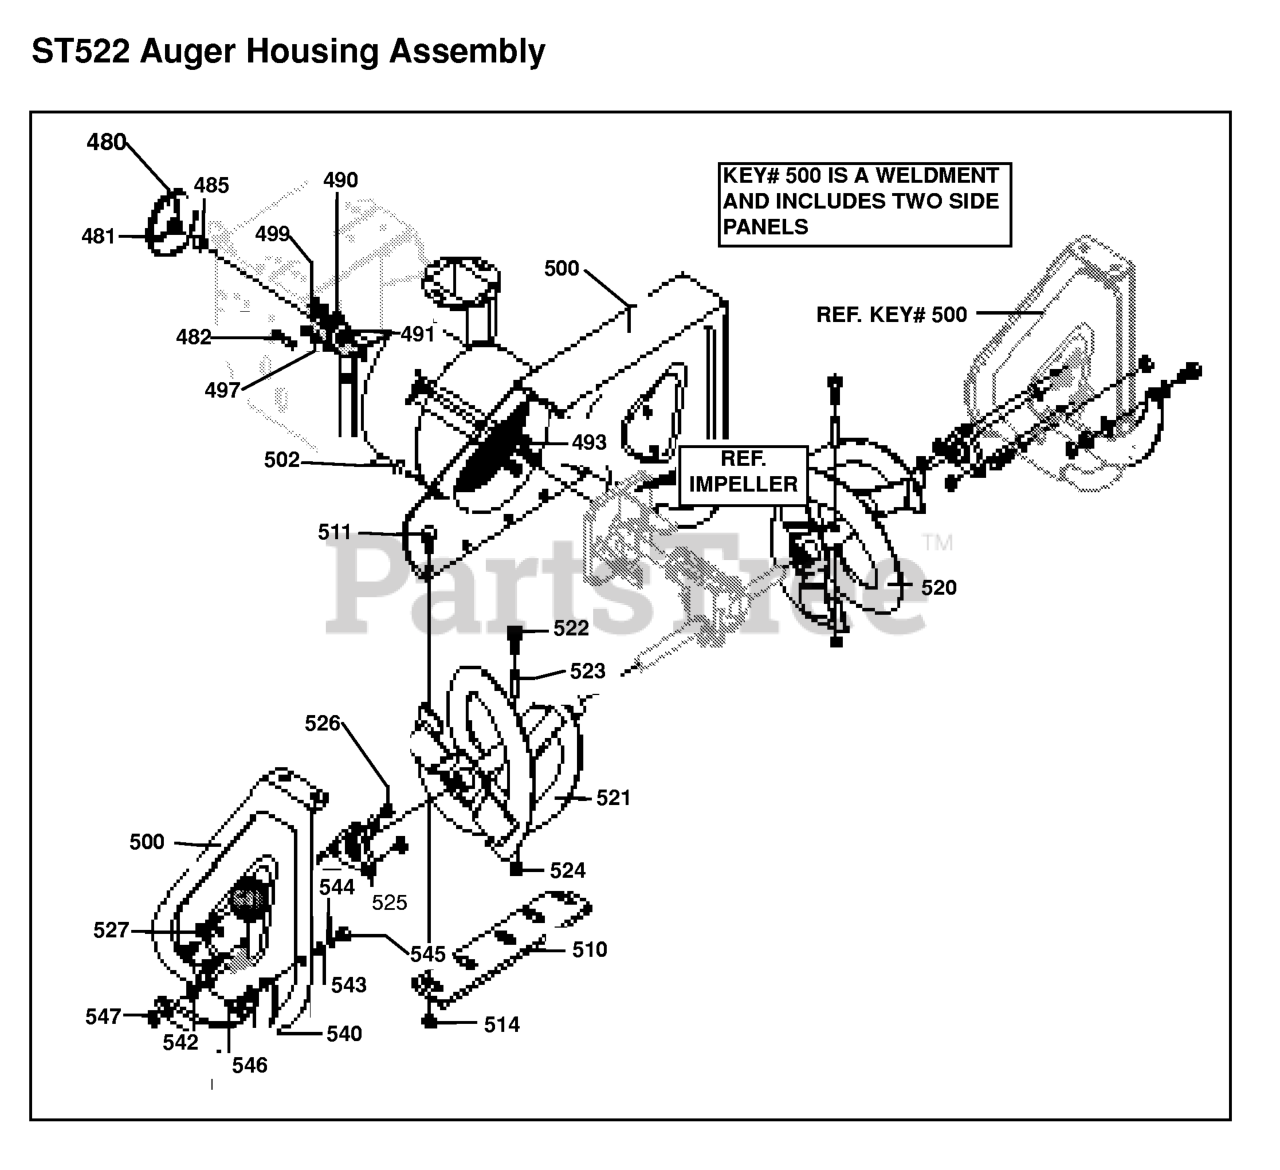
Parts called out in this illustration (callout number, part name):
480	PULLEY, V4L
481	Washer, Pl .438 x .75 x .064
482	SQUARE KEY
485	SPACER, SLEV .676X1.00X.53
491	BEARING
493	SCREW, 5/16-18X .75 HHC
497	WASHER, HVSPTLK .328X.60X
499	NUT, 5/16-18 REGHEX
500	HOUSING ASSY
502	RATCHET FASTENER
510	BLADE, SCRAPER 22"
511	CARRIAGE BOLT
514	Nut, 1/4-20 Whiz-loc
520	Auger, Assy LH
521	Auger, Assy RH
525	Bearing, Flange
526	Nut, 5/16-18, HXWDFLLK
527	SCREW, 5/16-18X.75
540	Skid, Edge Cover
542	WASHER, FLAT .391X1.00X.
543	WASHER, FLAT .344X .69X.
544	WASHER, HVSPTLK .328X.60X
545	NUT, 5/16-18 REGHEX
546	SCREW, 5/16-18X .75 HHC
647	Nut, 5/16-18, HXWDFLLK
